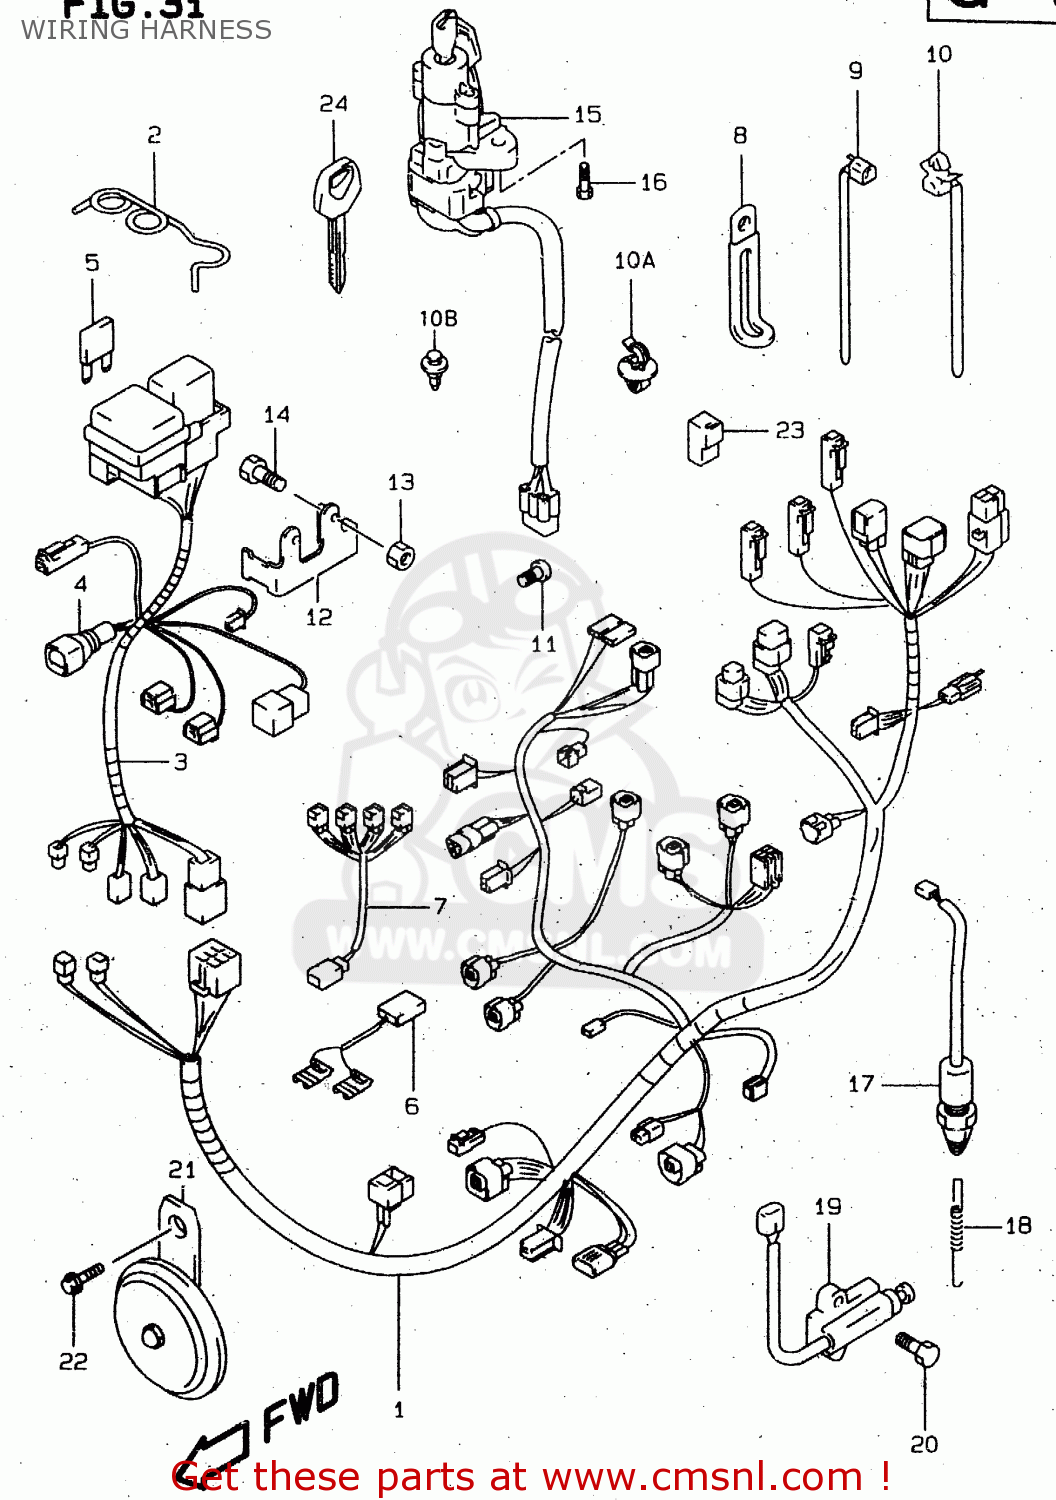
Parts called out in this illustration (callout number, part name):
1	HARNESS,WIRING NO.1
2	GUIDE,WIRING HARNESS
3	HARNESS,WIRING NO.2
4	COVER,SPEEDOMETER COUPLER
5	FUSE(10A)
6	WIRE,IGNITION COIL LEAD
7	WIRE,INJECTION LEAD
8	CLAMP(L:65)
9	CLAMP(L:125)
10	CLAMP
10A	CLAMP
10B	CLIP(BLACK)
11	BOLT
12	BRACKET,FUSE BOX
13	NUT,COWLING SCREEN
14	SCREW 5X12
15	LOCK ASSY,STEERING
16	BOLT(8X20)
17	SWITCH ASSY,STOP LAMP
18	SPRING
19	SWITCH ASSY,SIDE STAND WARNING
20	BOLT
21	HORN ASSY
22	BOLT
23	RELAY ASSY
24	KEY,BLANK
